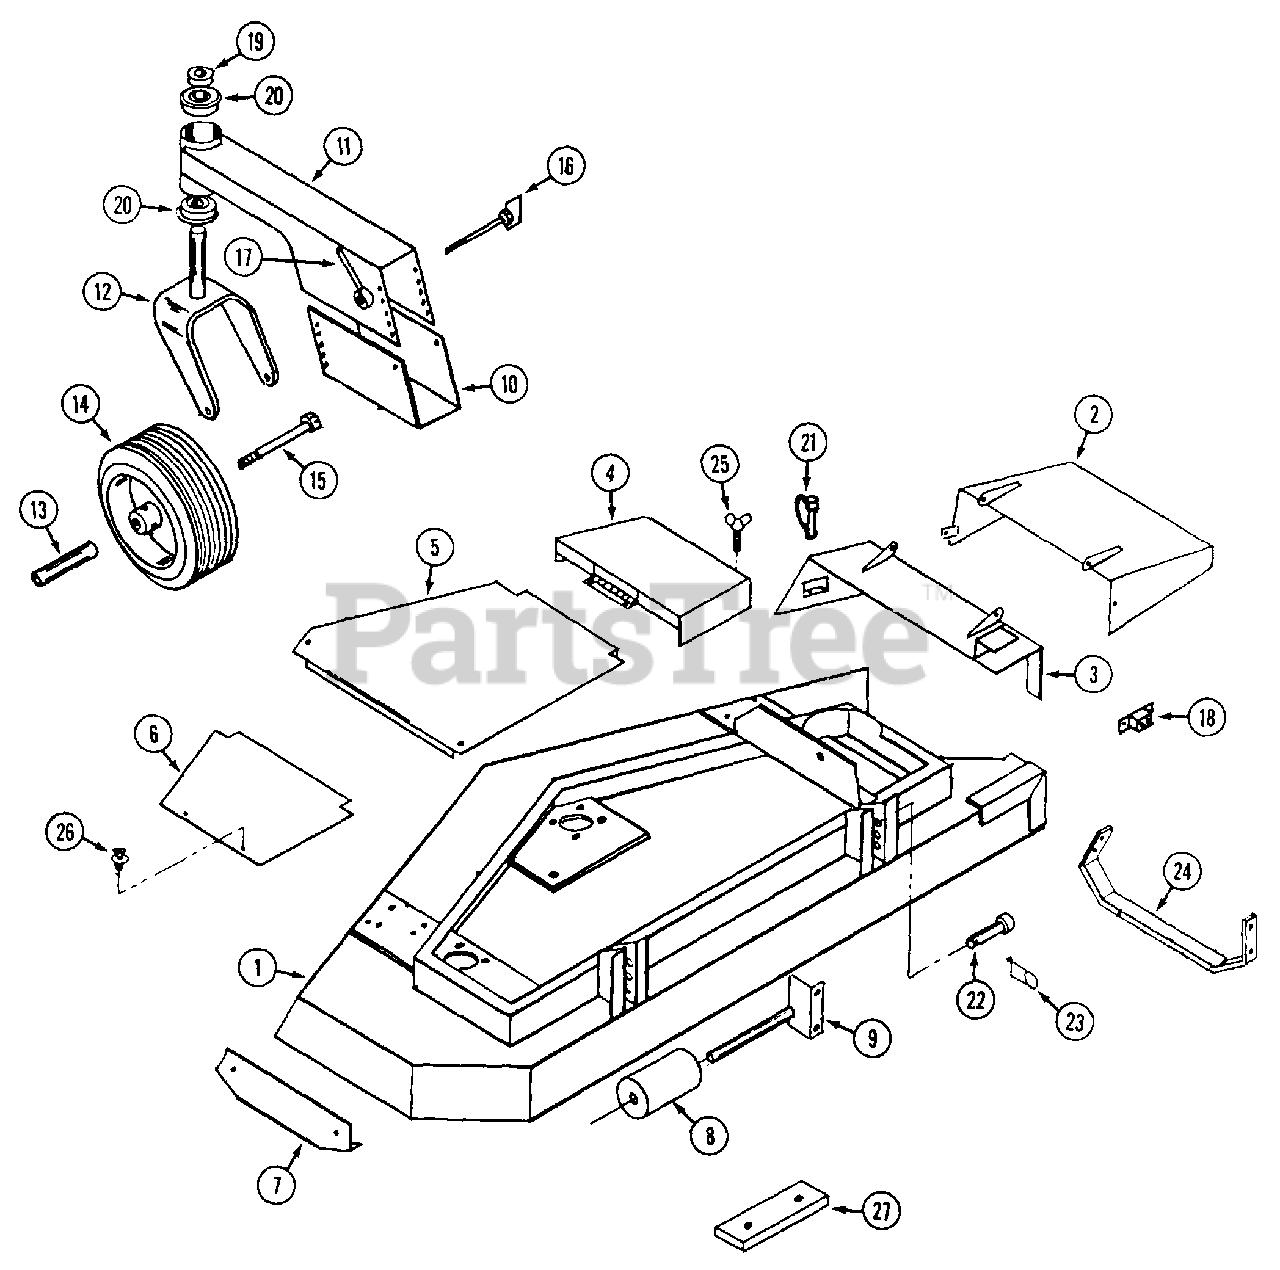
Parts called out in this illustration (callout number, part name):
1	DECK - 62"
2	CHUTE - foot guard
3	MOUNT - foot guard
4	COVER - pulley
5	COVER - center
7	SHOE - skid L.H.
8	ROLLER - anti-skid
9	SHAFT - roller
10	BRACKET - gauge wheel mount
11	MOUNT - gauge wheel
12	FORK - gauge wheel
13	AXLE - gauge wheel
15	BOLT - 1/2"-13 x 6-1/2"
17	NUT - gauge wheel handle
18	BREAKER - circuit - 10 amp
19	COLLAR - set 1"
21	PIN - "fas-tatch"
23	PIN - cotter, hair
24	SHOE - skid R.H.
27	WEIGHT - tail, 13 lb.
